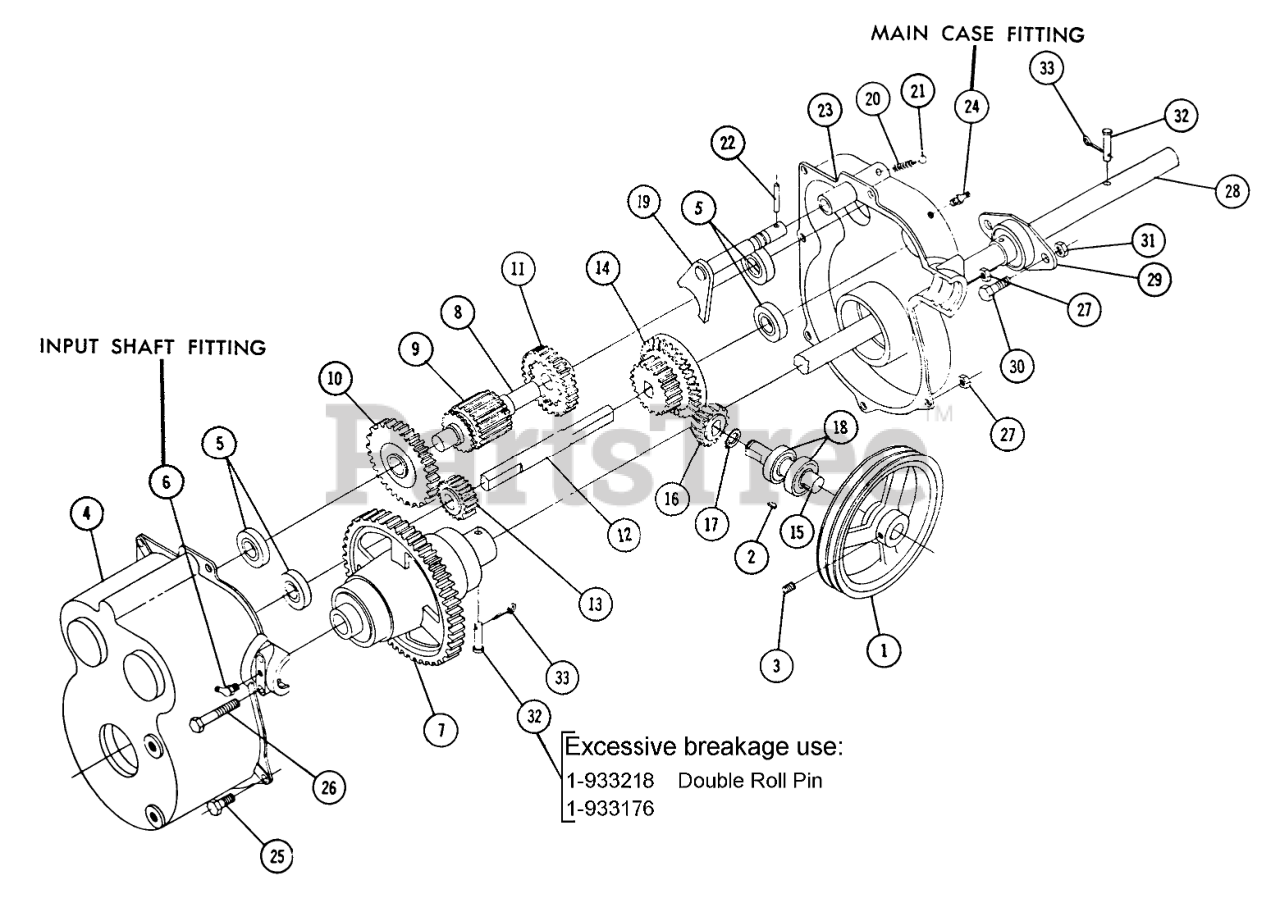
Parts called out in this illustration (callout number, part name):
3	Set Screw-Nylok
6	FITTING-GREASE
17	SNAP RING- 5/8 EXT
21	BALL-DETENT
22	PIN-SPIROL
25	Bolt, 5/16-18 X 7/8
26	Bolt Hex 5/6-18 X 2-1/2
27	Nut 5/16-18 Keps
30	Bolt Hex 3/8-16 x 5/8
31	Nut
32	Clevis Pin 1/4 x 1 1/2
33	Hairpin
